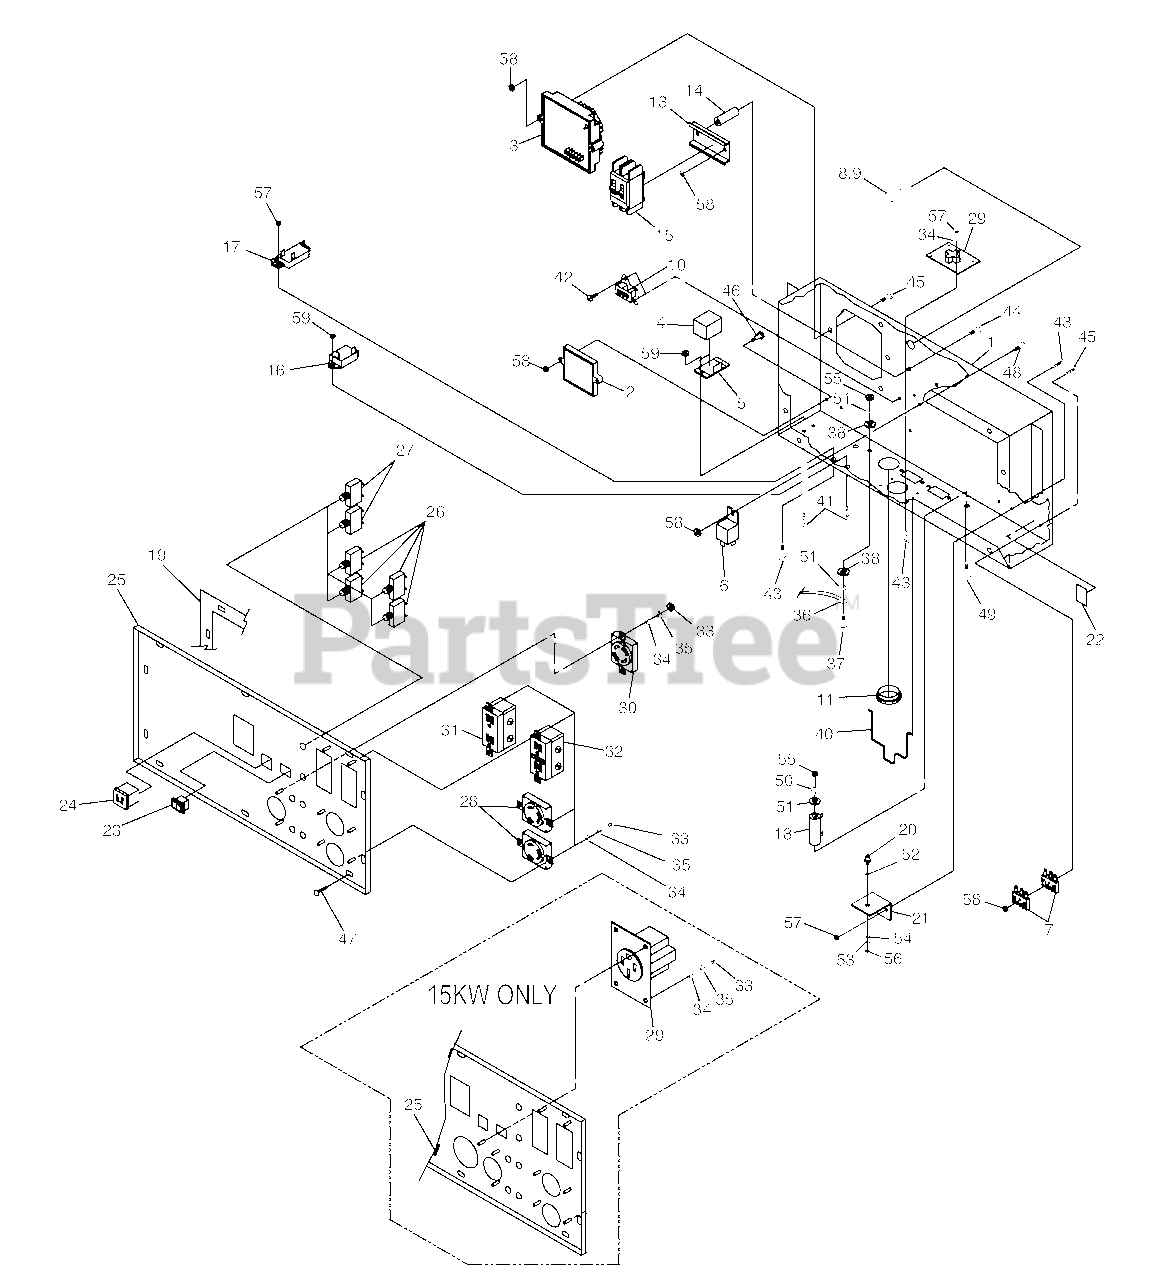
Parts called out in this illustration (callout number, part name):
1	CONTROL PANEL BOX (15 KW)
2	ELECTRONIC GOVERNOR / IDLE CONTROLLER
3	ASSY PCB VREG AIR COOLED
4	RELAY 3PDT 12VDC
5	RELAY BASE 3PDT 12VDC
6	RELAY PNL 12VDC SPST 30A
7	RECTIFIER-BATTERY CHARGER
8	HOLDER FUSE
9	FUSE 10A X AGC10
10	TRANSFORMER, IDLE CURRENT
11	BUSHING SNAP
13	DIN RAIL 59.5mm LONG
14	SPACER .25 X .50 X 2.5 (17.5 KW)
15	CIRCUIT BREAKER 50A 400V 2POLE
16	CIRCUIT BREAKER 10A 1POLE
17	CIRCUIT BREAKER 6A 1POLE
18	RESISTOR 25R 5% 25W
19	GASKET, PORTABLE CONTROL PANEL
20	RECTIFIER 1N1206R
21	HEATSINK
22	TAPE ELEC UL PERMACEL
23	SWITCH, ROCKER -/0
24	OUTLET, 12VDC SNAP
25	PANEL, SHEET METAL (15 KW)
26	CIRCUIT BREAKER 30A
27	CIRCUIT BREAKER 20A
28	OUTLET 30A 120V RECEPT
29	OUTLET 50A 125/250V
30	OUTLET 30A 125/250V
31	OUTLET 20A 120V DPLX
32	OUTLET 20A 120V GFCI
33	NUT HEX M4-0.7 (15 KW)
34	WASHER FLAT #8 (15 KW)
35	WASHER LOCK M4 (15 KW)
36	GROUND WIRE
37	SCREW HHC M6-1.0 X 35
38	WASHER LOCK SPECIAL 1/4"
40	SPRING RETAINER (17.5 KW)
41	SCREW PPHM M3-0.5 X 12
42	SCREW PPHM M3-0.5 X 8
43	SCREW PPHM M4-0.7 X 10
44	SCREW PPHM M5-0.8 X 80 (17.5 KW)
45	SCREW PPHM M5-0.8 X 30
46	SCREW HHC M5-0.8 X 25
47	SCREW HHTT M5-0.8 X 10
48	SCREW HHC M5-0.8 X 10
49	SCREW HHC M6-1.0 X 65
50	WASHER LOCK M6 (1/4")
51	WASHER FLAT 1/4"
52	WASHER MICA .203
53	WASHER FLAT #10
54	WASHER STEP NYLON .20
55	NUT HEX M6-1.0
56	NUT HEX #10-32
57	NUT HEX M4-0.5 NYINS
58	NUT HEX M5-0.8 NYINS
59	NUT HEX M3-0.5 NYINS
